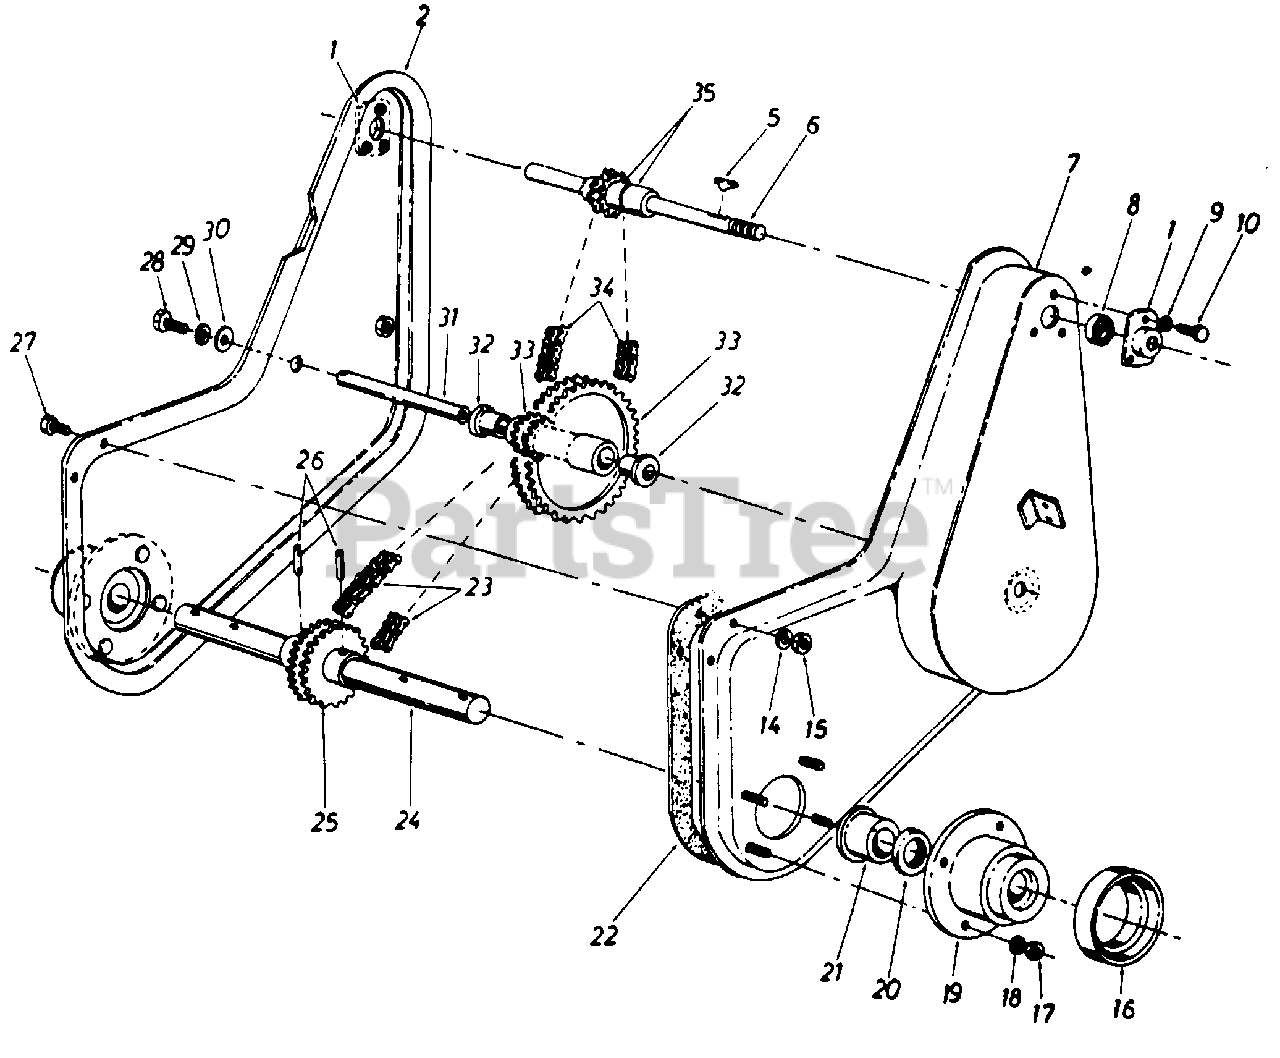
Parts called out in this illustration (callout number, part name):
1	Bearing Housing 1.375 Dia.
6	Input Shaft Assernbly
9	L-Wash. 1/4" I.D.
10	Hex Bolt t1/4-20 x .62" Lg.
14	L-Wash. l/4" I.D.
15	Hex Cent. L-Nut 1/4-20 Thd.
16	Dust Cap Cover
17	Hex Cent. L-Nut 5/16-18 Thd.
18	L-Wash. 5/16 I.D.
19	Cast Bearing Housing
20	Oil Seal
21	Flange Bearing 1.25" I.D. x 1.75" O.D.
22	Gasket
23	Roller Chain #40-2 x 34.0" Lg.
24	Tine Shaft
25	Double Sprocket T242 Teeth 1/2" Pitch
26	Spiral Pin 3/8 Dia. x 2.00 Lg.
27	Hex Bolt 1/4-20 x .62" Lg.
28	Hex Bolt 5/16-18 X .75" Lg.
29	L-Wash. 5/16" I.D.
30	Fl-Wash. 5/16" I.D.
31	Sprocket Shaft
32	Flange Bearing .62" I.D. x .75" O.D.
33	Double Sprocket Assembly
34	Roller Chain #35-2 X 36.75" Lg.
35	Spacer 5/8 I.D. x 7/8 O.D.
